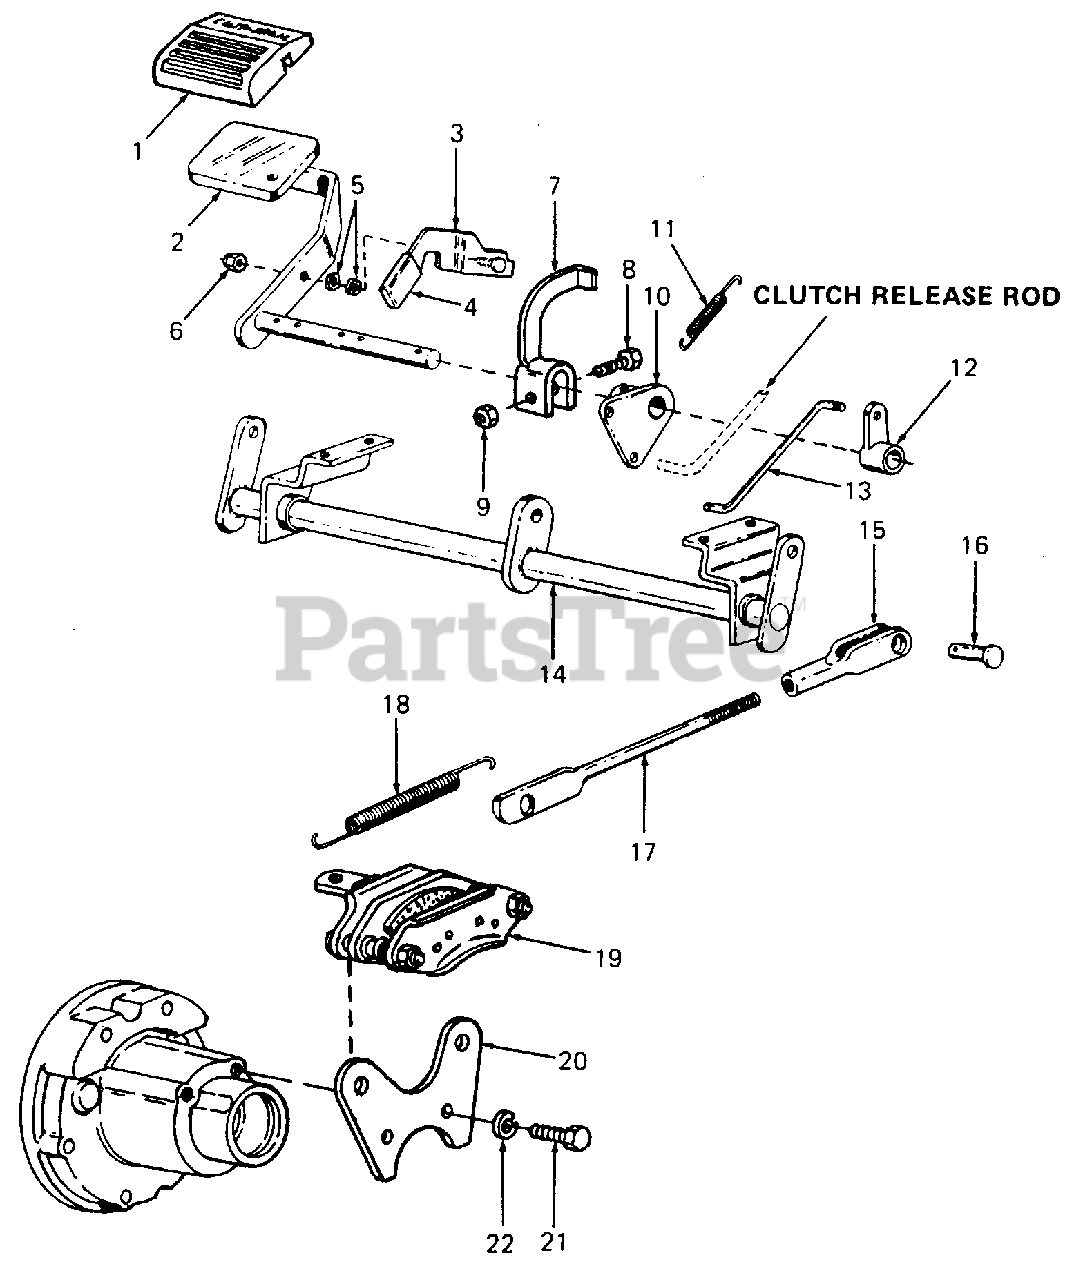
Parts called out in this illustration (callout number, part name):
1	Pad, Clutch/Brake Pedal
2	Pedal Assy, Brake
5	Washer, Wave, 1/4 Dia
6	Nut, Hex Insert Lock, 1/4-20
9	Nut, Hex Center Lock, 1/4-20
13	Rod, Brake Link
14	Shaft Assy, Brake
15	Clevis, Adjustment
16	Pin, Clevis, 3/8 Dia X 1.0 Lg
17	Rod, Brake
18	Spring, Tension
19	Kit, Brake Caliper
20	Bracket, Brake Mounting
21	Screw, Hex Cap, 5/16-18 X 1.0 Lg GR5
22	Washer, Lock, 5/16
